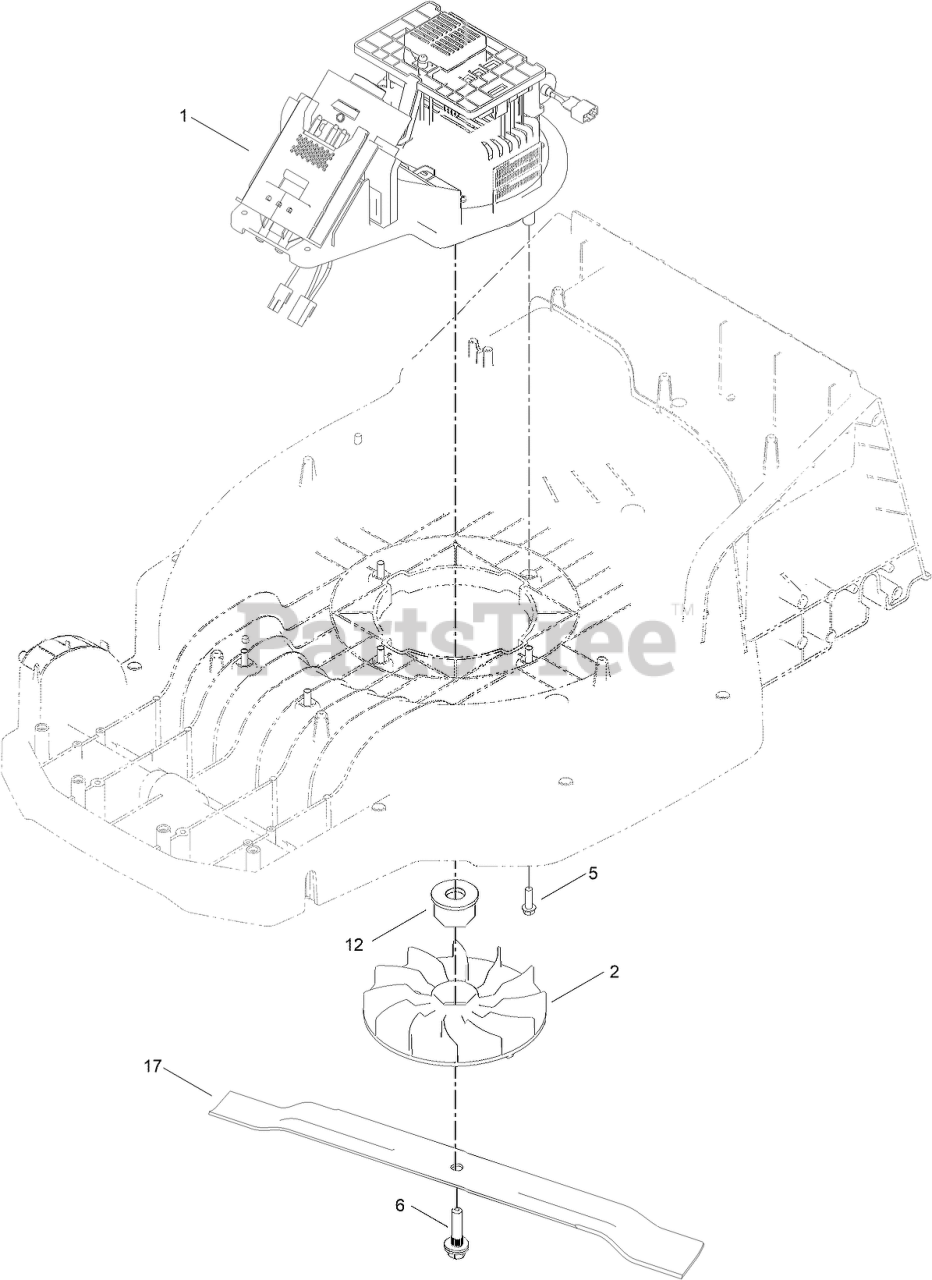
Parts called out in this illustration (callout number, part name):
1	ASM-POWER, COBRA HP
2	FAN-MOTOR
5	SCREW-HWH
6	BOLT-BLADE, SEMS
12	INSERT-FAN, MOTOR
17	BLADE-20.25
